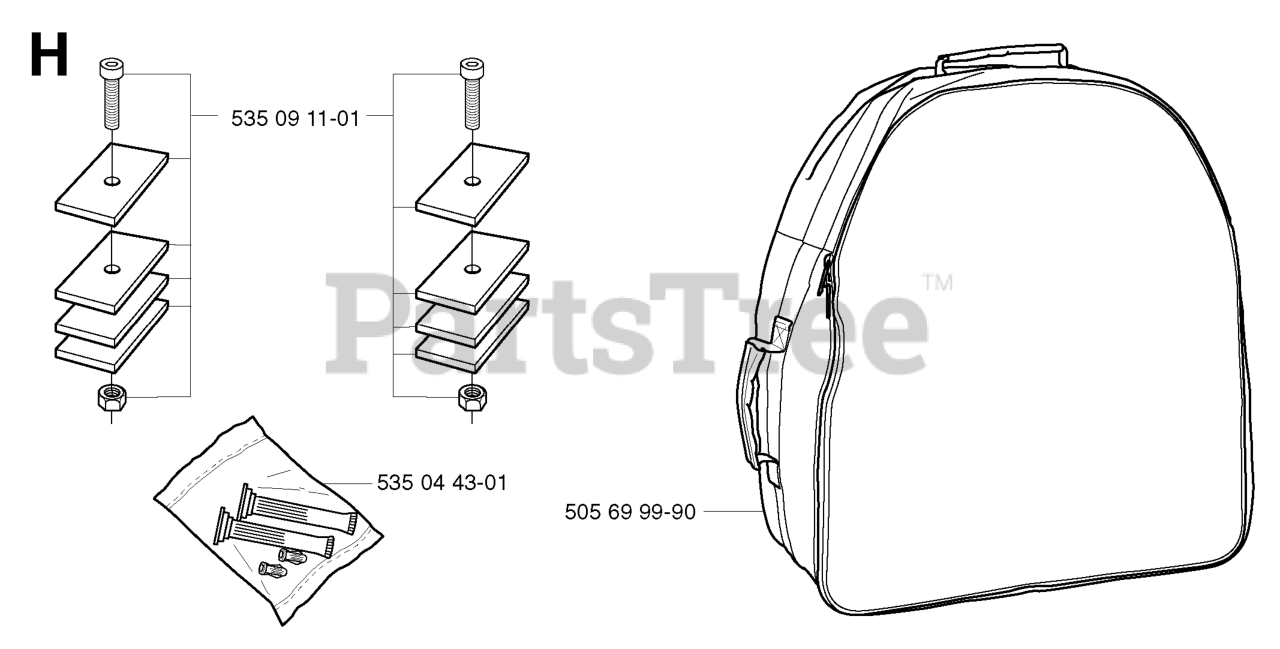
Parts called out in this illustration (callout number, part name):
6	DECAL.WARN.KEEP.HAND.AWAY
8	DECAL, DASH
9	DECAL, FENDER
10	DECAL FENDER DANGER
14	DECAL V-BELT SCHEMATIC
15	DECAL.WHEEL.STEERING.HUSQ.PERM
17	DECAL PARK BRAKE
23	REFLECTOR-TAIL YT
24	DECAL BTRY SYMBOLS
27	DECAL.BYPASS.FENDER.CRD.LT.YT
